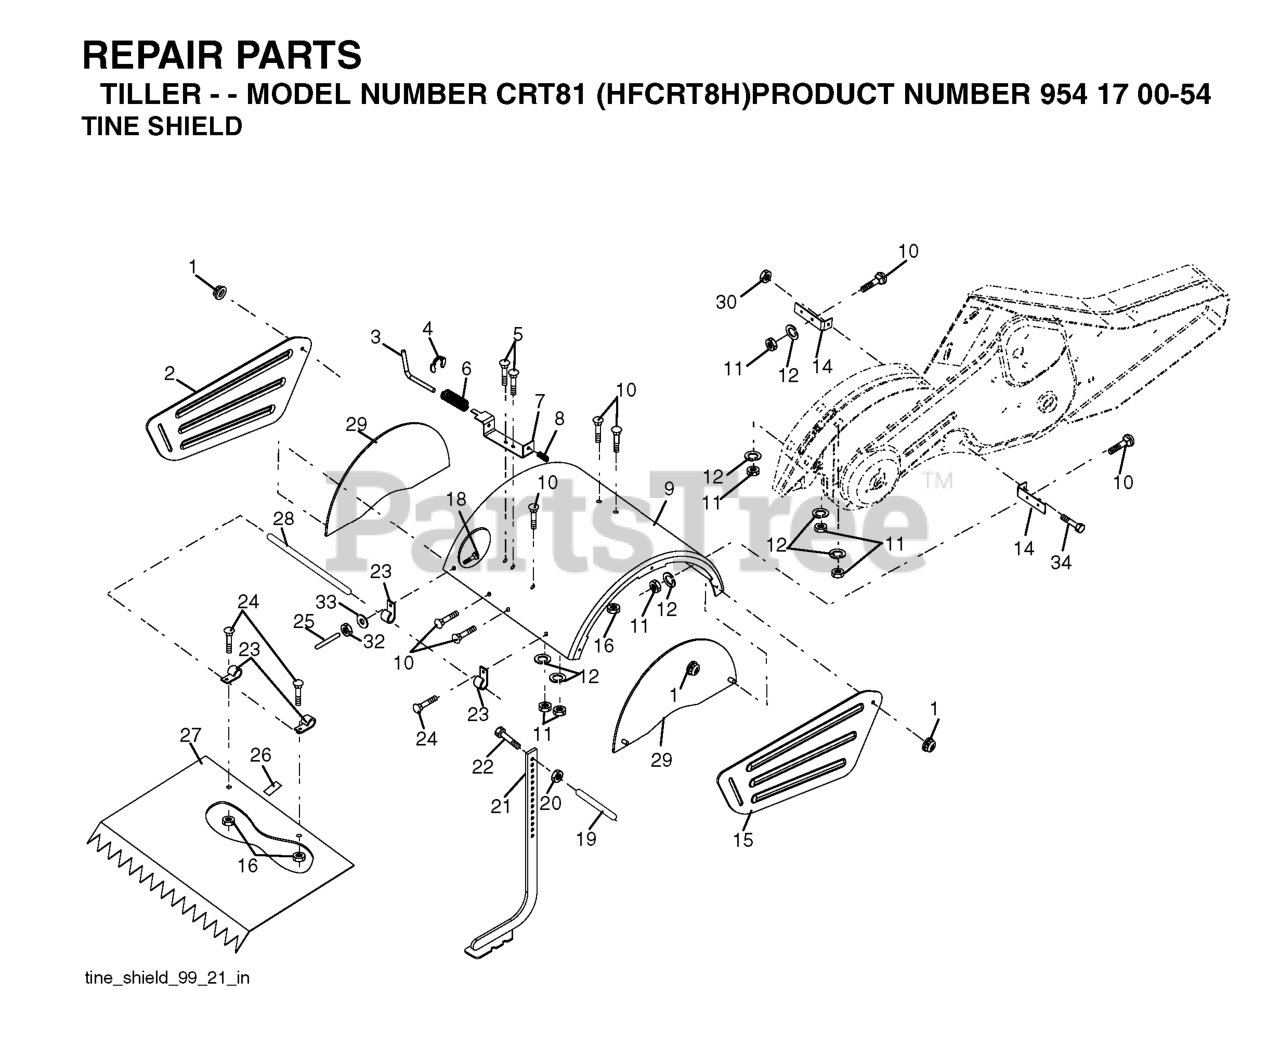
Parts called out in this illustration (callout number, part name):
1	NUT LOCK HEX FLANGE 5/16-18
2	TINE SHIELD
3	STAKE PIN TI
4	RING, KLIP
7	BRACKET.LATCH.STAKE.3.20.BLACK
8	SPRING CRT
9	SHIELD TINE
10	BOLT, RDHD SQNK 5/16-18 X 3/4
12	WASHER.LOCK.HVY.HLCL.SPR.5/16
14	BRACKET.TINE.SHIELD.TILLER
15	SHIELD
16	NUT T
20	NUT.HEX.3/8-16UNC
21	STAKE.ASM.DEPTH
22	BOLT.375-16
25	VINYL CAP TI
26	PAD IDLER TI
27	SHIELD.LEVELING.21".ORANGE
28	PIN, HINGE
29	SHIELD, SIDE
30	LOCKNUT-FLANGE 5/16-18
32	NUT
33	LOCKWASHER
34	Bolt Hex Flanged 5/16-18 Unc x 2
